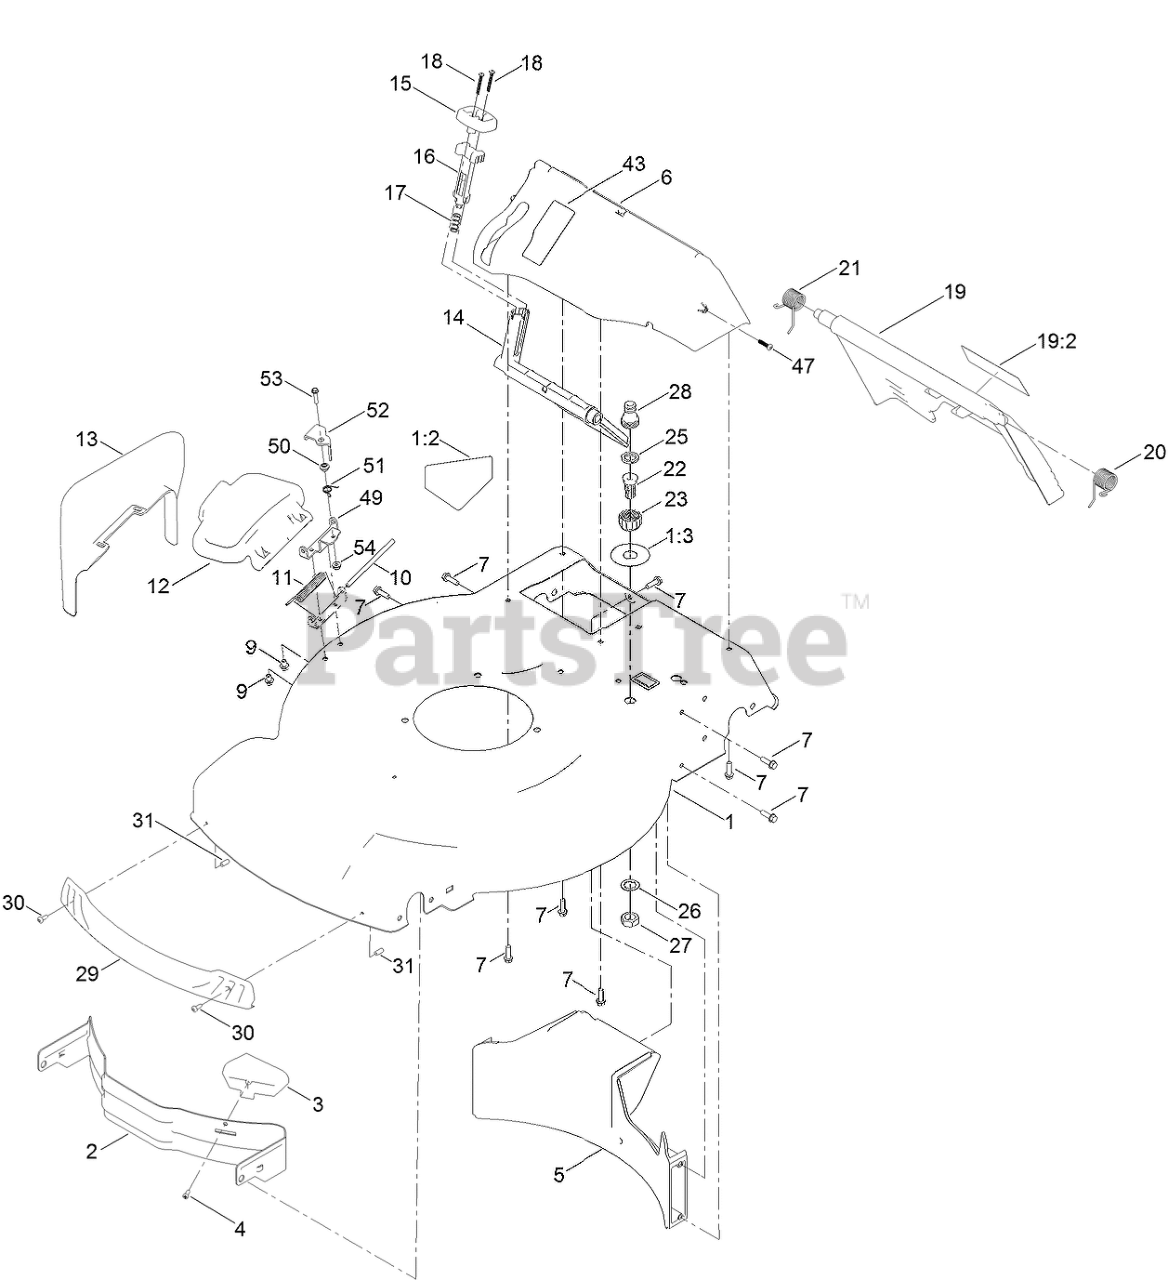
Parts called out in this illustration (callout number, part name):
1	HOUSING ASM
1:2	DECAL-DANGER
1:3	DECAL-QUICK WASH
2	BAFFLE-FRONT
3	KICKER-FRONT
4	SCREW-PPH
5	BAFFLE-REAR
6	CHUTE-RECYCLE
7	SCREW-HWH
9	SCREW-HWH
11	SPRING-TORSION
12	DEFLECTOR-SIDE
13	CHUTE-DISCHARGE, SIDE
14	DEFLECTOR-RECYCLE
15	KNOB-RECYCLE
16	LATCH-RECYCLE
17	SPRING-COMPRESSION
18	SCREW-PPH
19	REAR DOOR ASM
19:2	DECAL-WARNING
20	SPRING-TORSION
21	SPRING-TORSION
22	PORT-WASHOUT
23	COUPLING-HOSE, WASHOUT PORT
25	WASHER-SEAL, WASHOUT PORT
26	WASHER-LOCK
27	NUT-JAM
28	ADAPTER-CONNECT, QUICK
29	BUMPER
30	SCREW-FORMING, THREAD
31	CAP-PLUG
47	SCREW-PLASTITE
49	BRACKET-LOCKOUT
50	SPACER
51	SPRING-TORSION
52	LEVER-LOCKOUT
53	SCREW-HWH
54	NUT-LOCK, FLANGE
